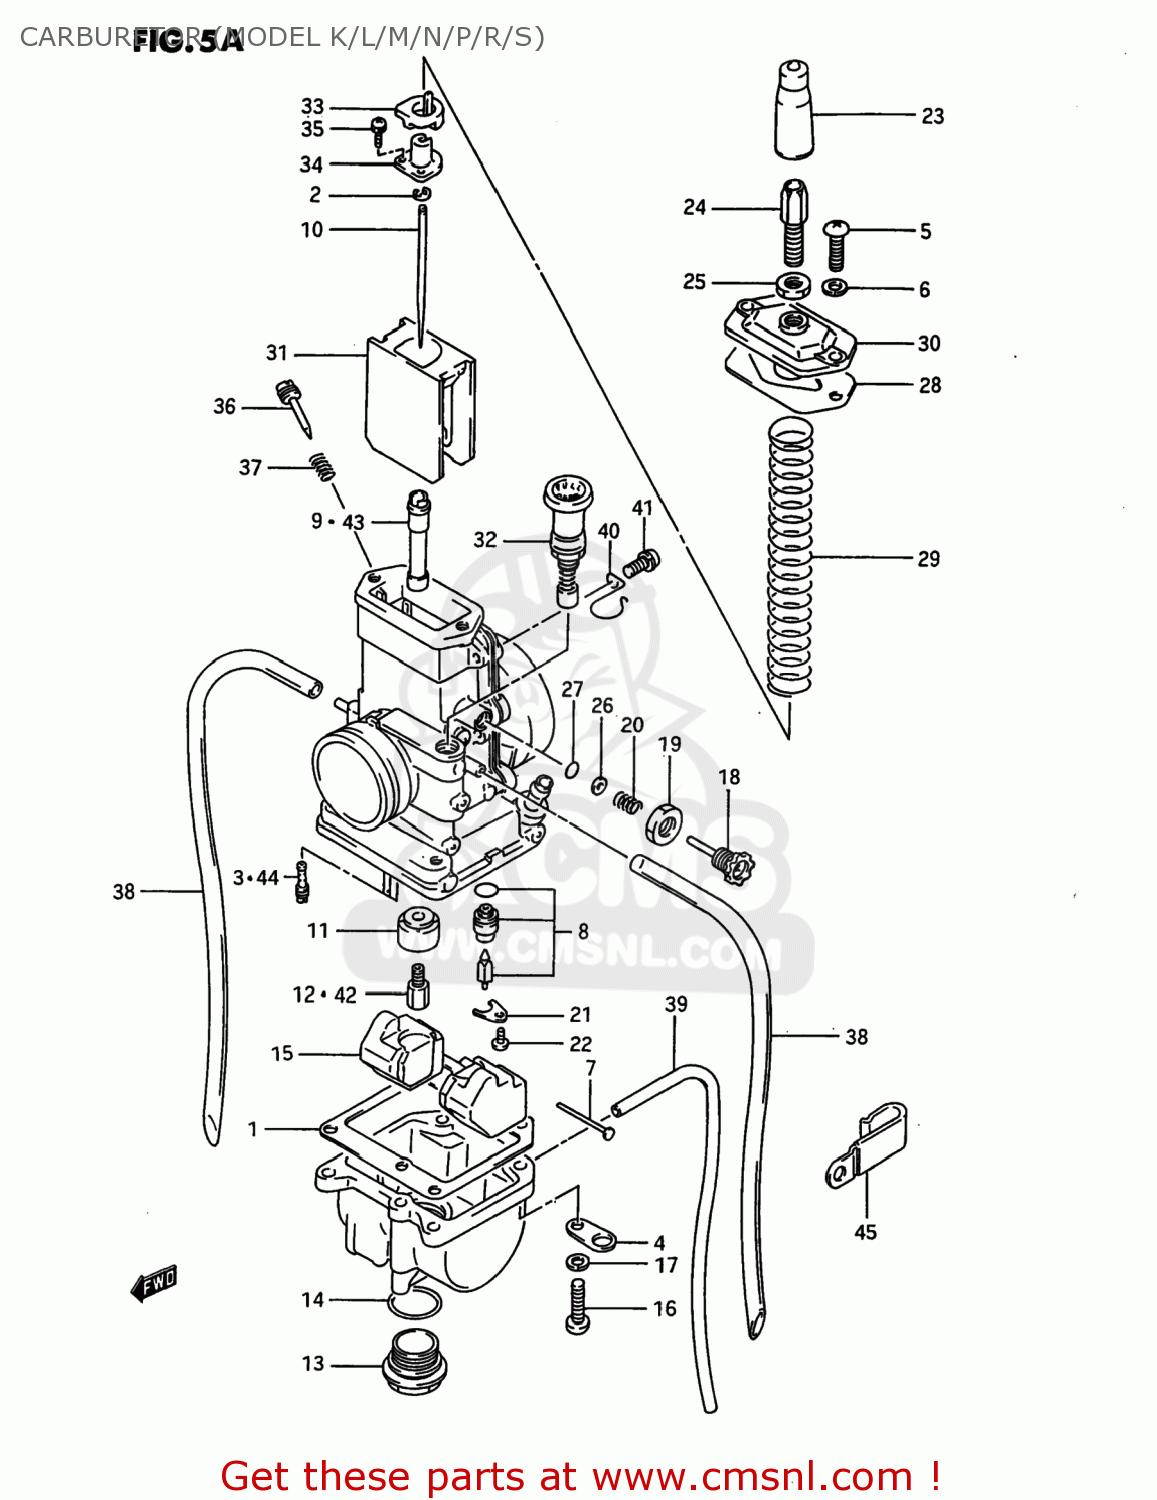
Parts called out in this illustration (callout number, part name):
1	GASKET,FLOAT CHAMBER (NAS)
2	CLIP
3	JET,PILOT(30)
4	PLATE,CARBURETOR
5	SCREW
6	WASHER,LOCK
7	PIN,FLOAT
8	VALVE ASSY,NEEDLE
9	JET,NEEDLE(P-4)
10	NEEDLE,JET(5DP39-4)
11	RING
12	JET,MAIN(200)
13	PLUG
14	O RING
15	FLOAT
16	SCREW
17	WASHER,LOCK
18	ADJUSTER,THROTTLE STOP
19	NUT
20	SPRING
21	PLATE
22	SCREW
23	CAP,CABLE ADJUSTER
24	ADJUSTER,CABLE
25	NUT
26	WASHER
27	O RING
28	GASKET,CARBURETOR TOP (NAS)
29	SPRING
30	CAP,CARBURETOR TOP
31	VALVE,THROTTLE
32	PLUNGER ASSY,STARTER
33	RING
34	JOINT
35	SCREW
36	SCREW,AIR
37	SPRING
38	HOSE(3.5X6.5X600)
39	HOSE(3X5X600)
40	CLIP
41	SCREW
42	JET,MAIN(170)
43	JET,NEEDLE,P-2
44	JET,PILOT(25)
45	CLAMP
